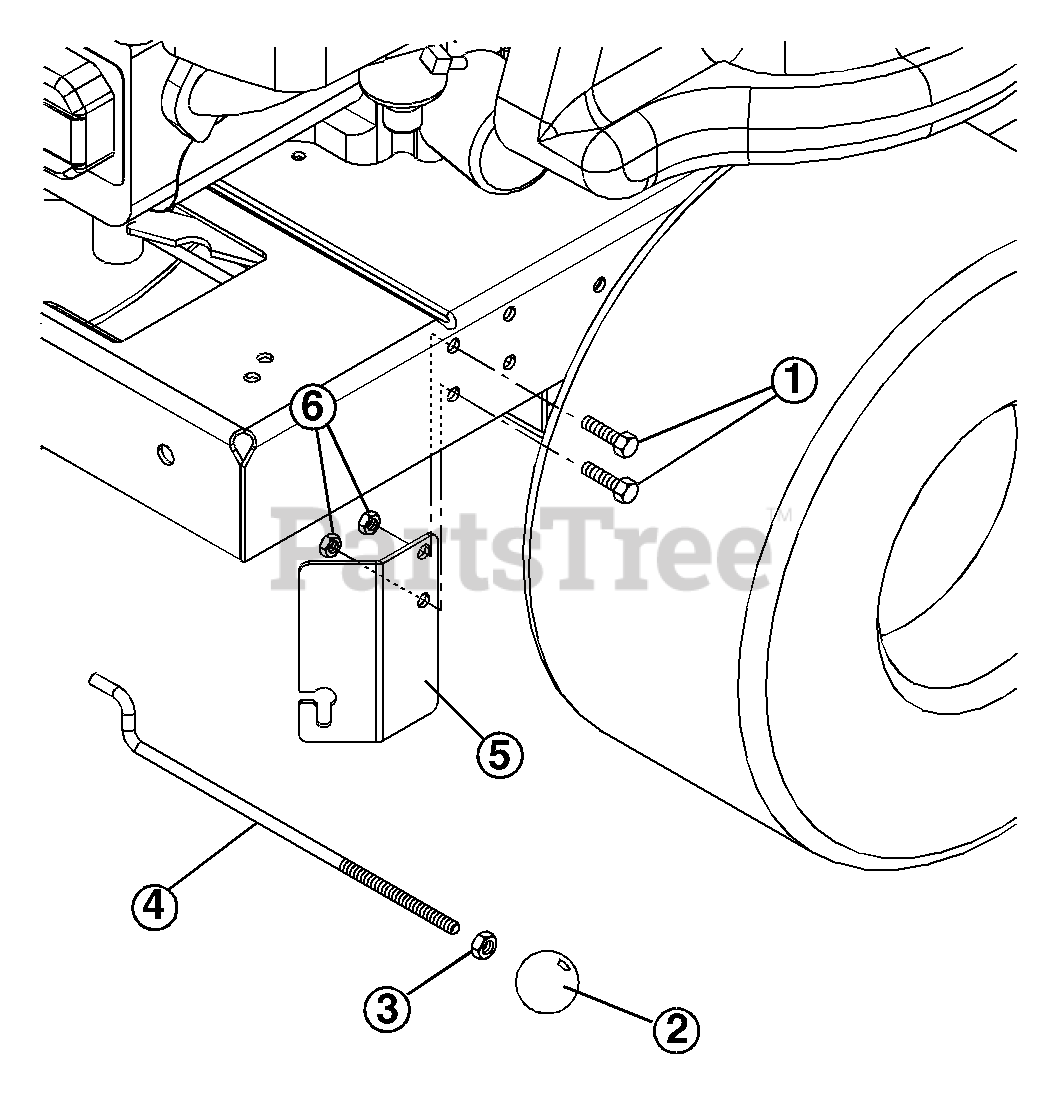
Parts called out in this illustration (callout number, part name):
1	@BLT-HEX .38-16X1.25 GR5 YWZC
2	KNOB, BALL 5/16-18 X 1.5
3	@NUT-HEX .31-18 YWZC
4	ROD, IDLER
5	BRACKET, COLD START
6	@NUT-LK-CTR .38-16 YWZC
